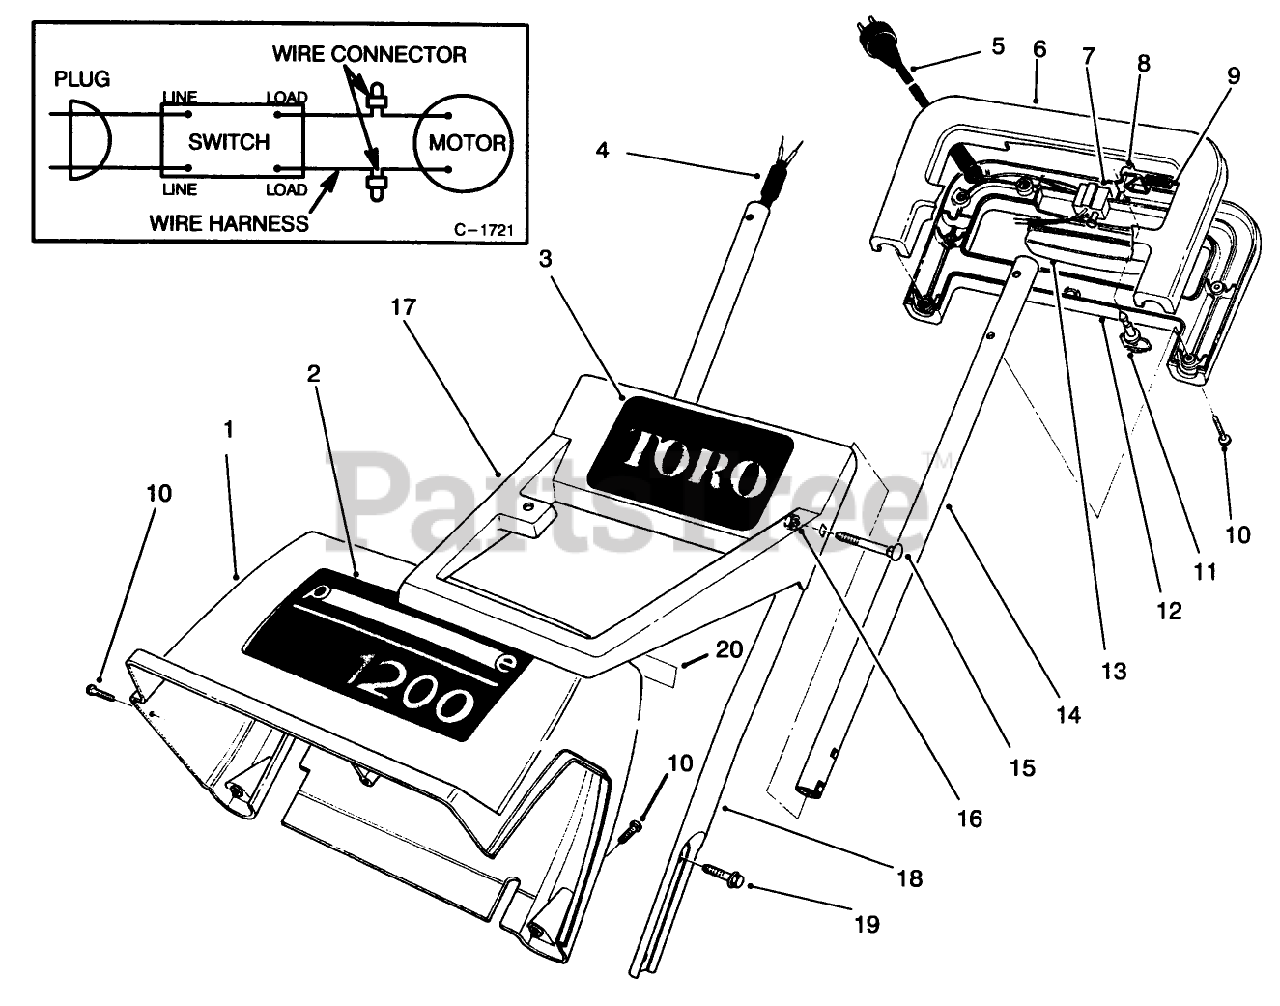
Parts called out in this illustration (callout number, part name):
1	Shroud (Incl. Ref. # 2 & 20)
2	DECAL-TORO 1200
3	DECAL-TORO
4	WIRE HARNESS
5	SUPPLY CORD, 1200
6	1200PC-CONTROL HANDLE U
7	SWITCH-STARTER
8	LOCKOUT, 1200
9	COMP SPRING
10	Screw
12	1200 P CONTROL HANDLE L
13	SWITCH BAR, 1200 PC
14	UPPER TUBE, S-120
16	NUT-LOCK, NI
17	MIDDLE HANDLE, 1200
18	LOWER TUBE, LH, S-120
19	SCREW-HWHTF
20	Decal-U.L.
